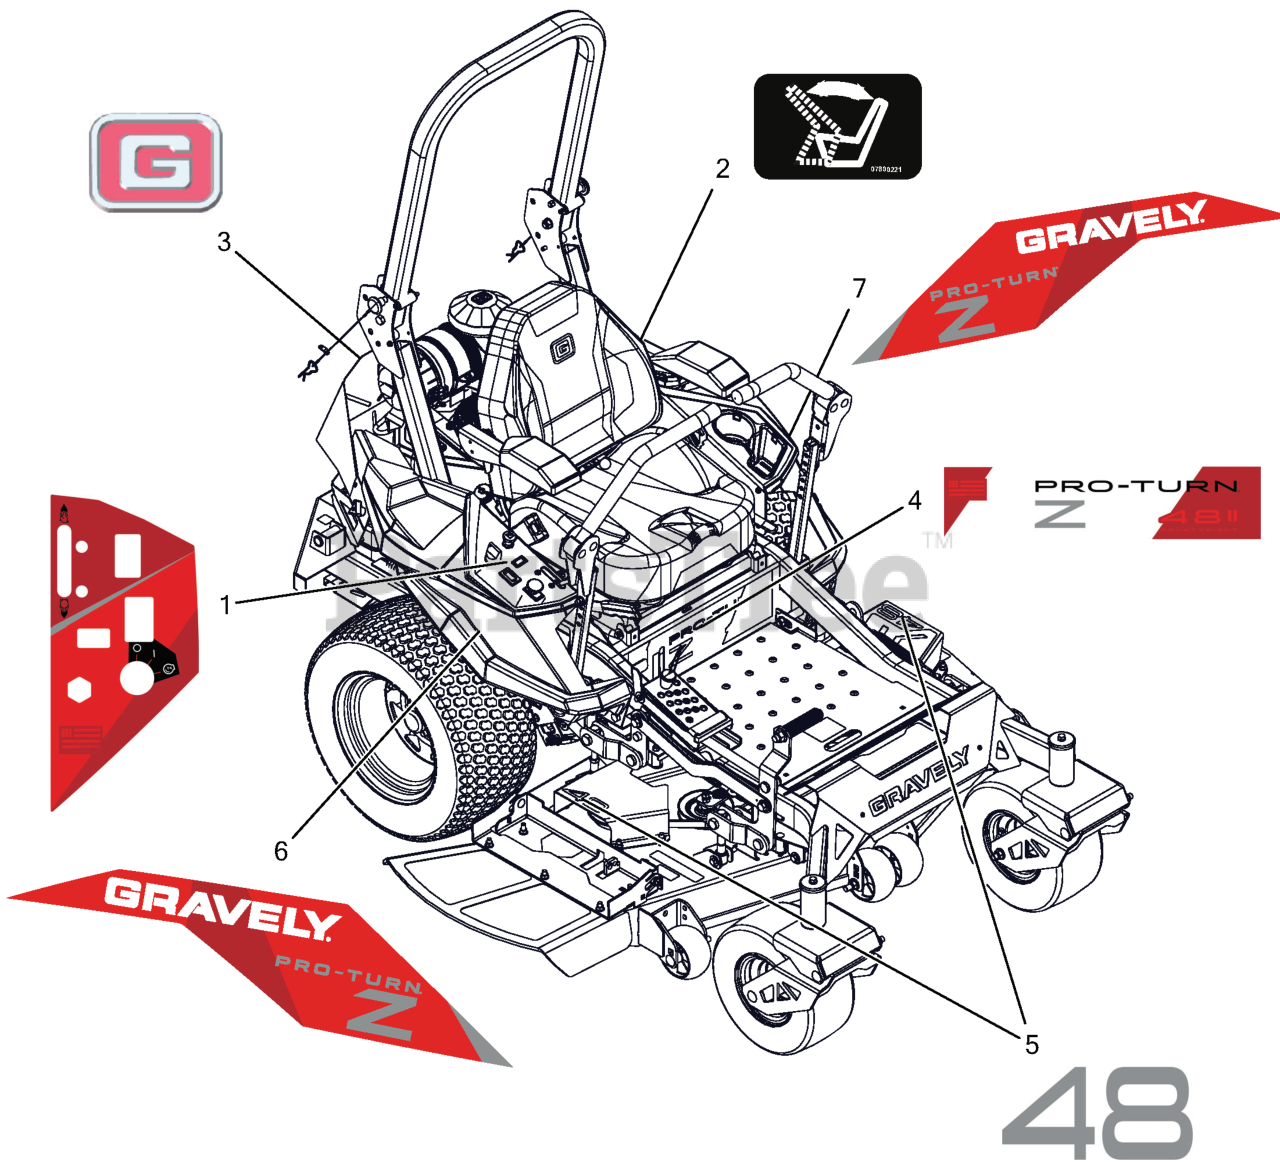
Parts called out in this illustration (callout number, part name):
1	DECAL, CONTROL PANEL
2	DECAL - SEAT RELEASE
3	DECAL, GRAVELY BRAND
4	DECAL, PTZ - 48
5	DECAL, DECK - 48
6	DECAL, FENDER RH - PTZ
7	DECAL, FENDER LH - PTZ
